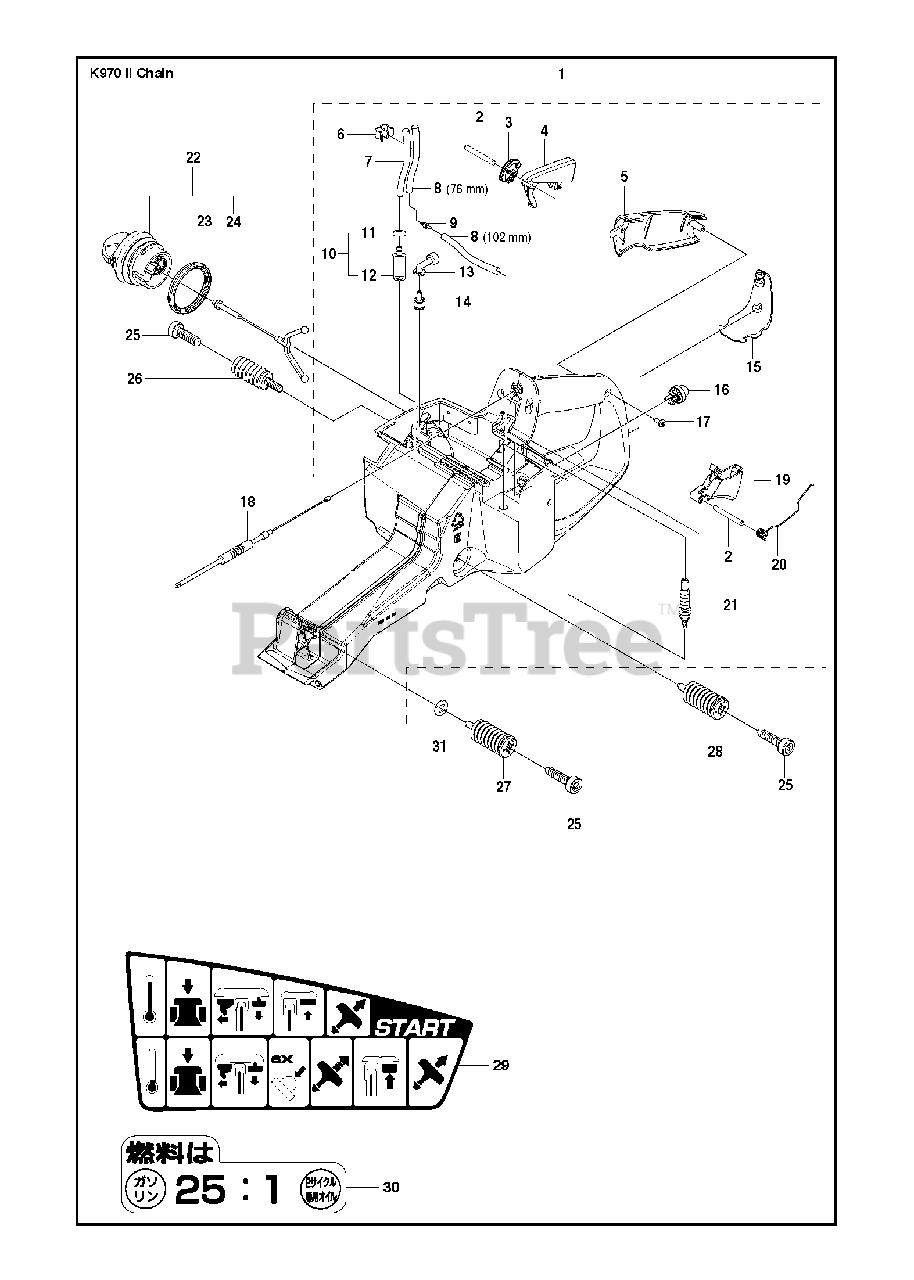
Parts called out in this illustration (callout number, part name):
1	FUEL TANK ASSYIncl. 2-21
2	PARALLEL PIN
4	THROTTLE LOCKOUT
7	FUEL HOSE
8	FUEL HOSE
13	TANK VENT ASSY
14	TANK VENT ASSY
15	GROUND SUPPORT
17	SCREW CITXPANT
18	THROTTLE CABLE ASSY
19	THROTTLE CONTROL
22	TANK CAP ASSY
25	SCREW ITXSCM
26	ANTIVIBRATION ELEMENT
27	ANTIVIBRATION ELEMENT
28	ANTIVIBRATION ELEMENT
